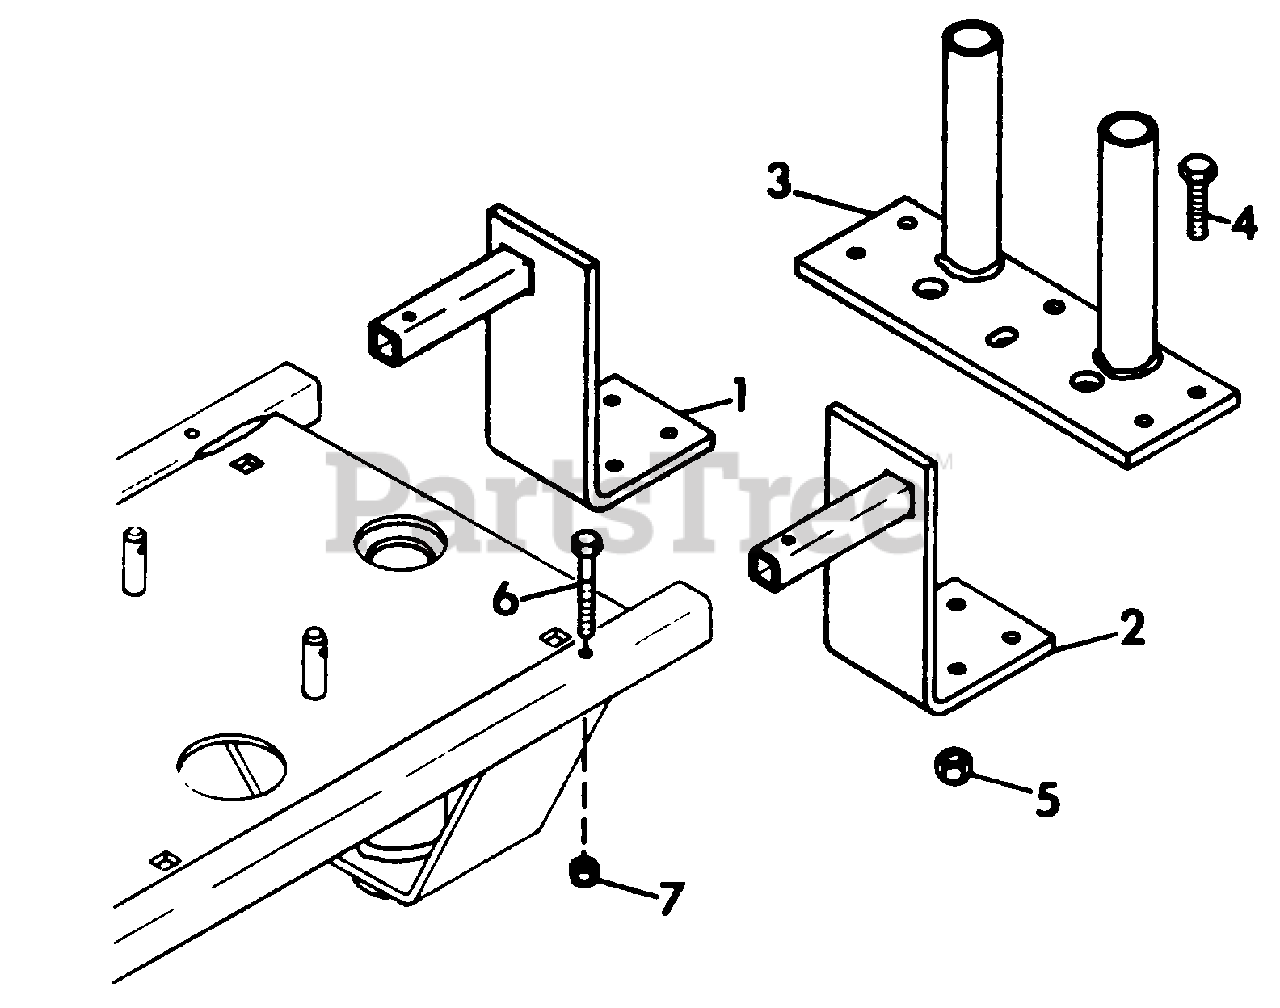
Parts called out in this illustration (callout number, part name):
1	WELDMENT, WEIGHT RACK, R.H.
2	WELDMENT, WEIGHT RACK, L.H.
3	SUPPORT, WEIGHT WELDMENT
4	BOLT, HEX 1/2-13 X 1.50
5	NUT, LOCK 1/2-13
6	BOLT, HEX 3/8-16 X 2.50
7	NUT, LOCK 3/8-16
